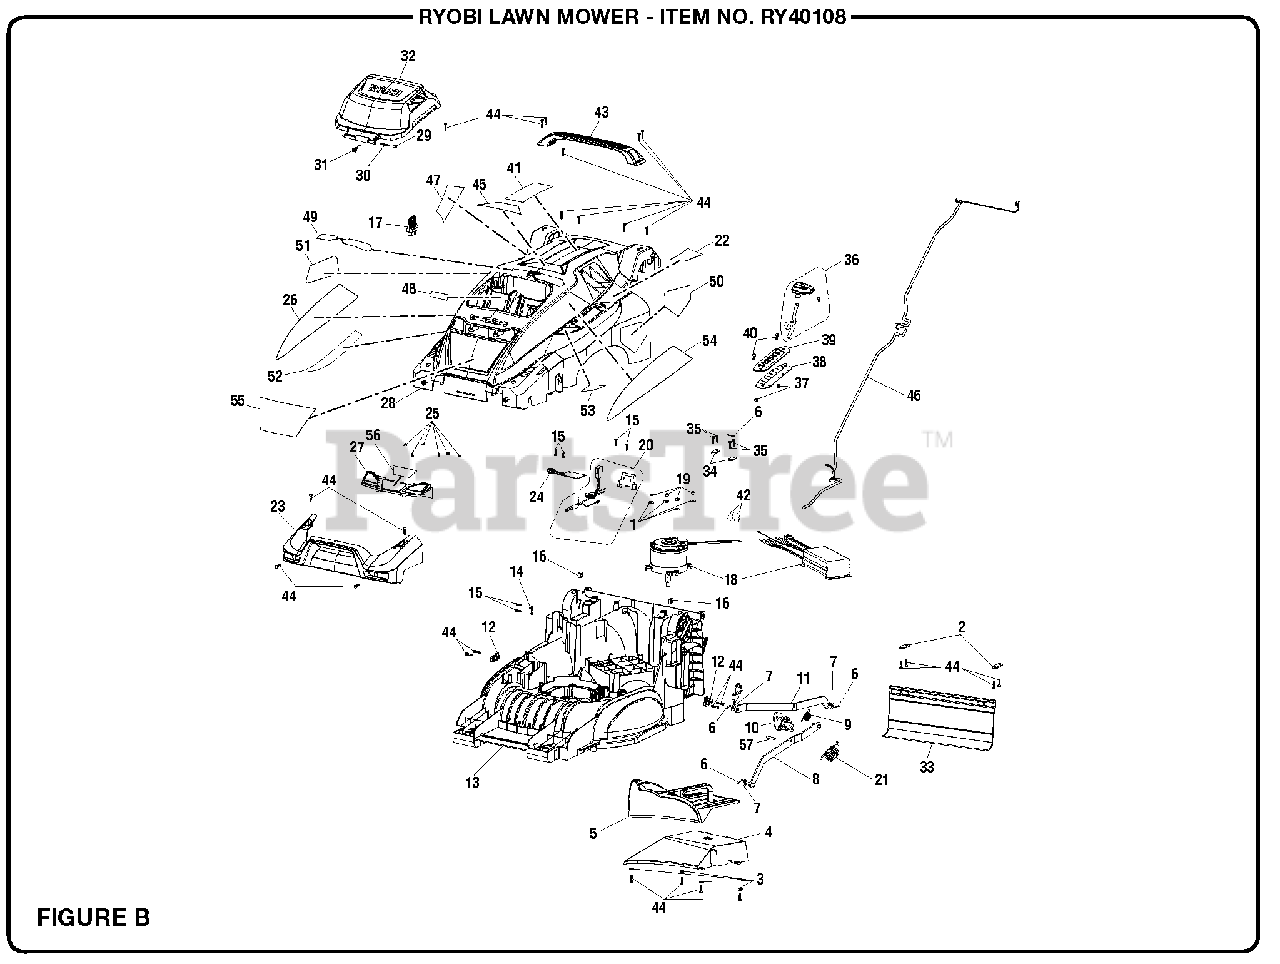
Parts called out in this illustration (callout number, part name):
1	Washer (ID6.2 x OD15 x 0.08t)
2	Axle Pressure Plate
3	Washer (ID4.5 x OD10 x 1t)
5	Mulching Plug
6	Cotter Pin
7	Washer (ID8.4 x OD18 x 1t)
8	Front Lift Rod
9	Torsion Spring (Height Adjustment)
10	Height Adjustment Bracket
11	Rear Lift Rod
12	Axle Mount
14	Cord Clip
15	Screw (M4 x 16 mm, T20 Torx Pan Hd.).
16	Square Nut (M8)
17	Start Key
18	Motor and Controller Assembly (EU17300 & Before, B.D.C. Week 30, 2017)
18	Motor and Controller Assembly (EU17301, A.D.C. Week 30, 2017)
19	Hex Nut (M6)
20	Key Holder Assembly
21	Rentention Spring
22	Height Adjustment Label
23	Front Bumper
24	Circuit Board (Before EU17171, B.D.C. Week 17, 2017 Light Assembly)
24	Circuit Board (EU17171, & After A.D.C. Week 17, 2017 Light Assembly)
25	Screw (M3 x 8 mm, Pan Hd.)
26	Brushless Label (Right)
27	Light Assembly
28	Deck Cover
30	Compression Spring
31	Torsion Spring
32	Battery Cover
33	Rear Protective Guard
34	Pressure Plate (Height Adjustment)
35	Screw (M4 x 18 mm, T20 Torx Pan Hd.)
36	Height Adjust Handle Kit
37	Hex Lock Nut (M5)
38	Dust Gasket
39	Height Adjustment Plate
40	Screw (M5 x 16 mm, Soc. Hd.)
41	Bilingual Danger (French/Spanish) & Trilingual Warning (English/French/Spanish) Label
42	Close-End Connector
43	Carrying Handle
44	Screw (M4 x 20 mm, T20 Torx Pan Hd.)
45	Danger/Warning Icon Label (English)
46	Wiring Harness (EU17151 & Before, B.D.C. Week 15, 2017)
46	Wiring Harness (EU17301 & After, A.D.C. Week 30, 2017)
46	Wiring Harness (EU17152-EU17300, A.D.C. Week 15, 2017 to B.D.C. Week 30, 2017)
47	40V Lithium Label
48	On Board Battery Storage Label
49	Warning Label
50	No Hands Label
51	Data Label
52	RYOBI Label (Right)
53	Logo Label
54	Brushless Label (Left)
55	40V Brushless Logo Label
56	LED Headlight Label
57	Adjust Height Axle
